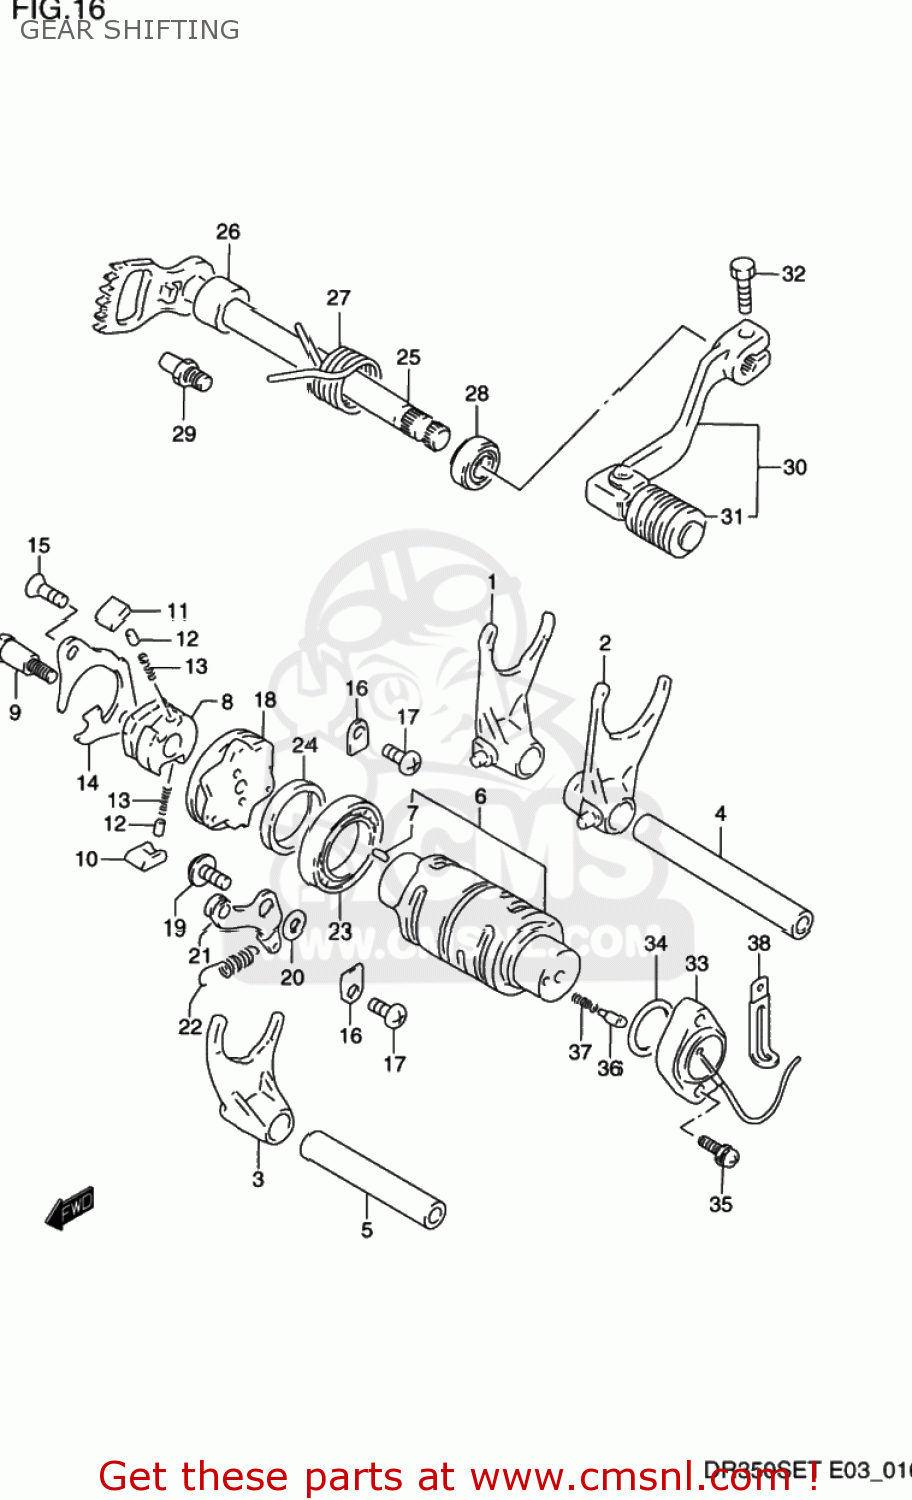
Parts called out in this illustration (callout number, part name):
1	FORK,GEAR SHIFT NO.1
2	FORK,GEAR SHIFT NO.2
3	FORK,GEAR SHIFT NO.3
4	SHAFT,GEAR SHIFT FORK
5	SHAFT,GEAR SHIFT FORK(L:70)
6	CAM,GEAR SHIFT
7	PIN
8	GEAR,GEARSHIFT CAM DRIVE
9	PIN,SHIFT CAM DRIVEN GEAR
10	PAWL,GEAR SHIFT NO.1
11	PAWL,GEAR SHIFT NO.2
12	PIN(5X8)
13	SPRING
14	LIFTER,GEAR SHIFT PAWL
15	SCREW
16	RETAINER
17	SCREW
18	PLATE,GEAR SHIFT CAM
19	BOLT(6X14.3)
20	WASHER
21	STOPPER,GEAR SHIFT CAM
22	SPRING
23	BEARING
24	WASHER(25X32X5.3)
25	SHAFT,GEAR SHIFT
26	SPACER(12X20X15.3)
27	SPRING
28	OIL SEAL
29	STOPPER,GEAR SHIFT ARM
30	LEVER ASSY,GEAR SHIFT
31	RUBBER,GEAR SHIFT PEDAL
32	BOLT
33	BASE ASSY,NEUTRAL SW TERMINAL
34	O RING(D:2.4,ID:26.2)
35	SCREW
36	PIN(5X15.5)
37	SPRING
38	CLAMP
